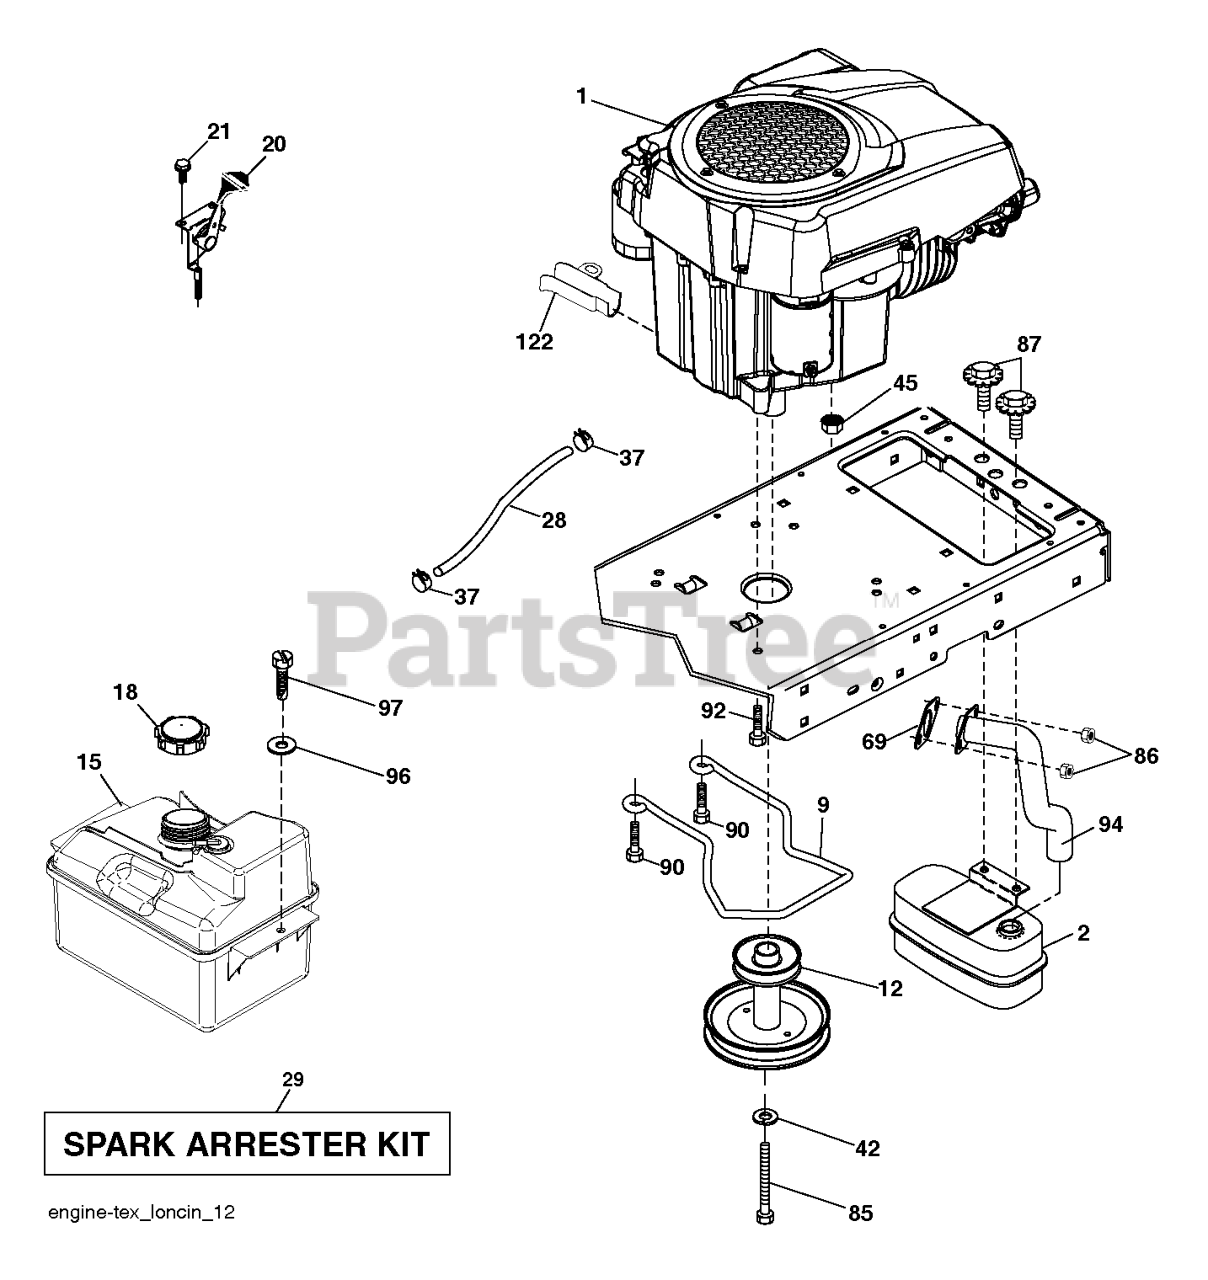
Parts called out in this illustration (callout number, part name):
1	ENGINE.LONCIN.SPARE/452
2	MUFFLER.ASM.SINGLE
9	KEEPER.BELT.ENG.3.25"2BOLT.PNT
12	PULLEY.ENG.CL.MECH.SLVR.LT/YT
15	FUEL.TANK.ASM.NON-EPA
18	CAP ASM.FUEL.2.25"FR.
20	CONTROL.TH/CK.C.
28	LINE.FUEL.20
29	KIT.SPARK ARRESTOR 794945 B&S
37	HOSE CLAMP
45	NUT HEXAGON WITH FLANGE, SERRA
69	GASKET GASKET.EXHAUST.LONCIN 3
85	BOLT.HEX.7/16-20X4.GR5.1.5BLUE
86	NUT.HEX.FLANGE.TOPLOCK
87	BOLT.5/16-18UNCX3/4 W/SEMS.BLK
90	SCREW 3/8-16X1
92	SCREW 3/8-16X1
94	TUBE TUBE.EXHAUST.LONCIN 452.T
97	SCREW HEXWSHR 1/4-20X3/4
122	EXTENSION DRAIN OIL
